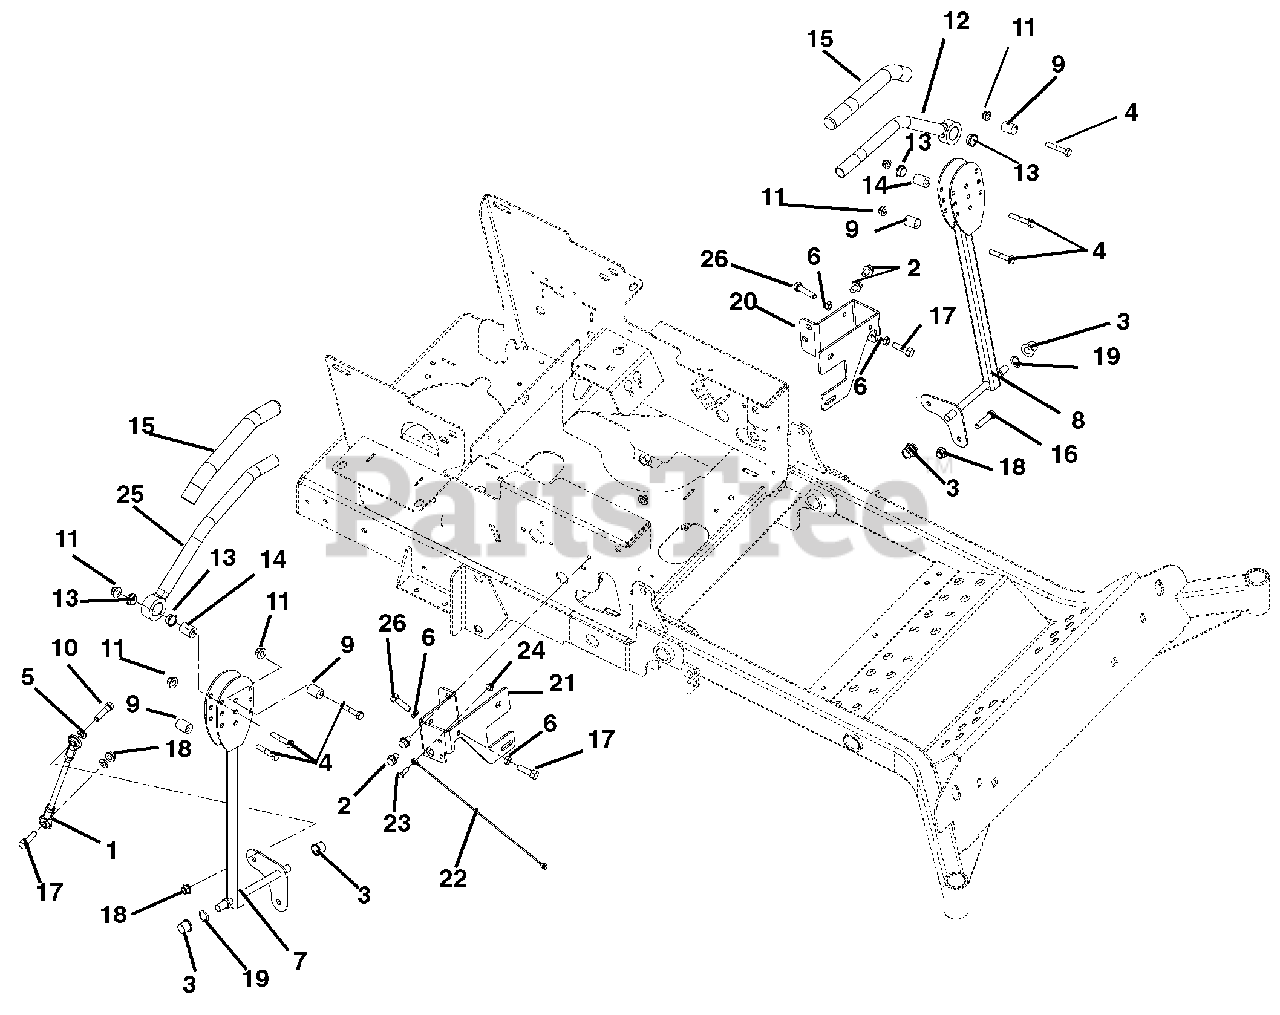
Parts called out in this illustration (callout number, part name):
1	Assembly, Steering Linkage
2	Screw, Tapping .38-16 x .50 Hex Washer Head
3	Bushing .625 x .75 x .50
4	Bolt, Hex .31-18 x 1.75 Grade 5
5	Washer, Locking .38 x .094
6	Nut, Hex Jam .375-16
7	Weldment, RH Control Arm
8	Weldment, LH Control Arm
9	Eccentric
10	Bolt, Hex .38-16 x 1.50 Grade 5
11	Nut, Nyloc Flange .375-16
12	Handle Weldment Left-Hand
13	Bushing, Flange Nylon .762 x 1.48 x .44
15	Grip, Handlebar
16	Bolt, Hex .375-16 x 2.00 Full Thread
17	Bolt, Hex .38-16 x 1.25 Grade 5
18	Nut, Nyloc Flange 3/8-16
19	Wave Washer
20	Stop, Steering-Left Hand
21	Stop, Steering-Right Hand
22	Cable, 12.0 LANYARD, Nylon
23	Bolt-Hex .25-20 x .75 Grade 5
24	Nut, Nyloc Flange .25-20
25	Handle Weldment Right-Hand
26	Bolt, Hex .38-16 x .75 Grade 5
